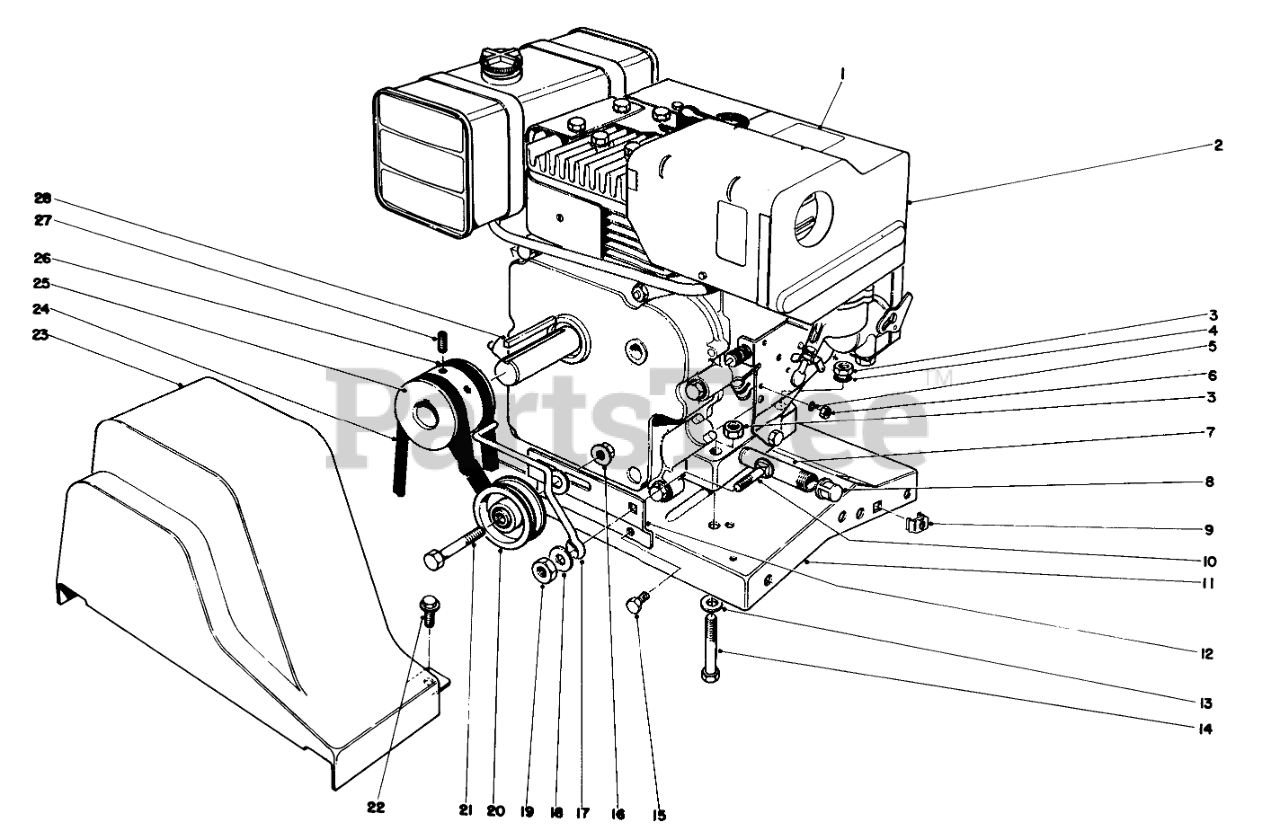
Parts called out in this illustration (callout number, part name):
1	Decal Instruction
2	Engine
3	NUT-LOCK, CONE
4	WASHER-LOCK, INTERNAL
5	WASHER-LOCK/INT
6	NUT-LOCK
7	NIPPLE-PIPE
8	Pipe Cap
9	Retained Nut
10	SCREW-CARR
11	Engine Base
12	Belt Idler Bracket
13	WASHER-PLAIN
14	SCREW-HH
15	SCREW-HHFTF
16	NUT-HHF, WHIZ
17	BELT GUIDE
18	WASHER-FLAT
19	NUT-HEX
20	PULLEY-IDLER
21	SCREW-HH
22	SCREW-HWH
23	BELT GUARD
24	V-BELT
25	Pulley
26	V-BELT
27	Screw-Set
